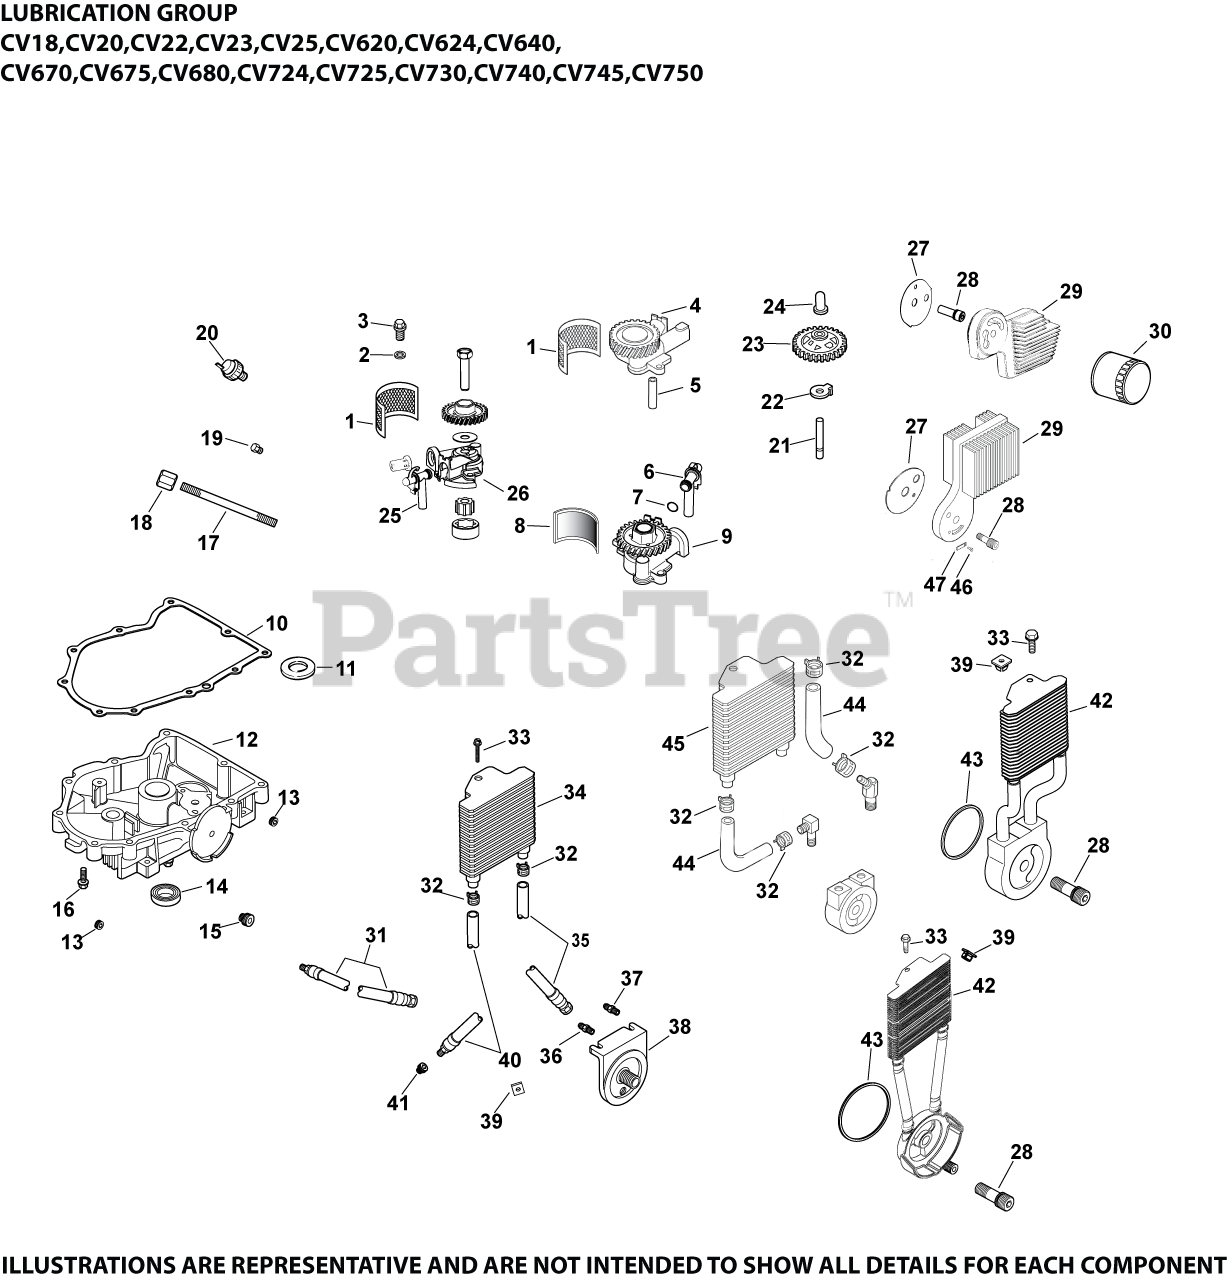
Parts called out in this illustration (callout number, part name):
2	WASHER, FLAT 6 MM
3	SCREW,FLG THD FRM M6X1.0X25-(#25086395S)
6	KIT, OIL PICK-UP TUBE
7	O-RING, OIL PICK-UP
8	SCREEN, OIL
9	PUMP ASSEMBLY, OIL-USE 24 393 53-S
10	KIT,OIL PAN GASKET USE 24 041 66-S
11	SHIM, THRUST
12	KIT, OIL PAN ASSEMBLY - (#2419932S)
13	PLUG, PIPE CTSK 3/8"
14	SEAL, OIL (KM)-USE 25 032 06-S
16	SCREW, FLG M8X1.25X45
16	SCREW, HEX FLANGE -USE 24 086 17-S
19	PLUG, HD PIPE 3/8"
20	SENSOR, OIL PSI
21	SHAFT, GOVERNOR GEAR
22	TAB, LOCKING
23	KIT, GOVERNOR GEAR W/PIN
24	PIN, GOVERNOR REGULATING
28	NIPPLE, OIL FILTER
30	OIL FILTER
33	SCREW, TAP M6X1.7X18
39	NUT, PLASTIC (KM)-USE 25 100 37-S
42	KIT, OIL COOLER
43	O-RING, OIL COOLER
